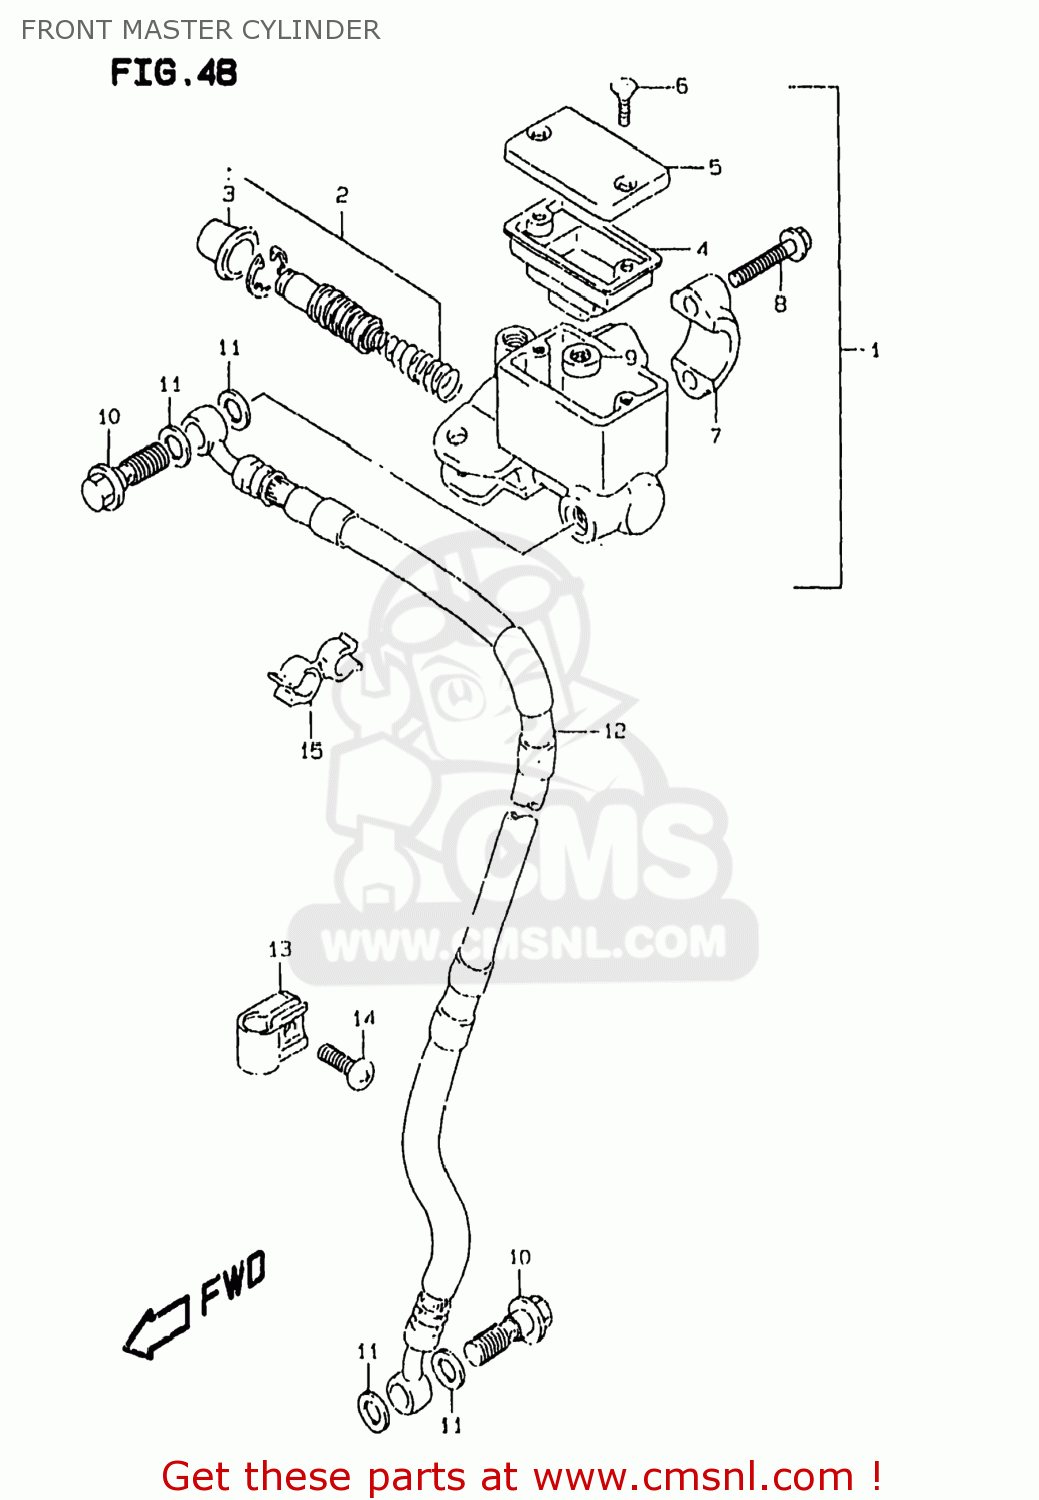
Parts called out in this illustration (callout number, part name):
1	CYLINDER ASSEMBLY,FRONT MASTER
2	PISTON/CUP SET
3	BOOT
4	DIAPHRAGM
5	CAP
6	SCREW
7	HOLDER
8	BOLT
9	SEPARATOR
10	BOLT UNION
11	WASHER(10X15X1.5)
12	HOSE,FR BRAKE
13	CLAMP,BRAKE HOSE
14	SCREW
15	CLIP
